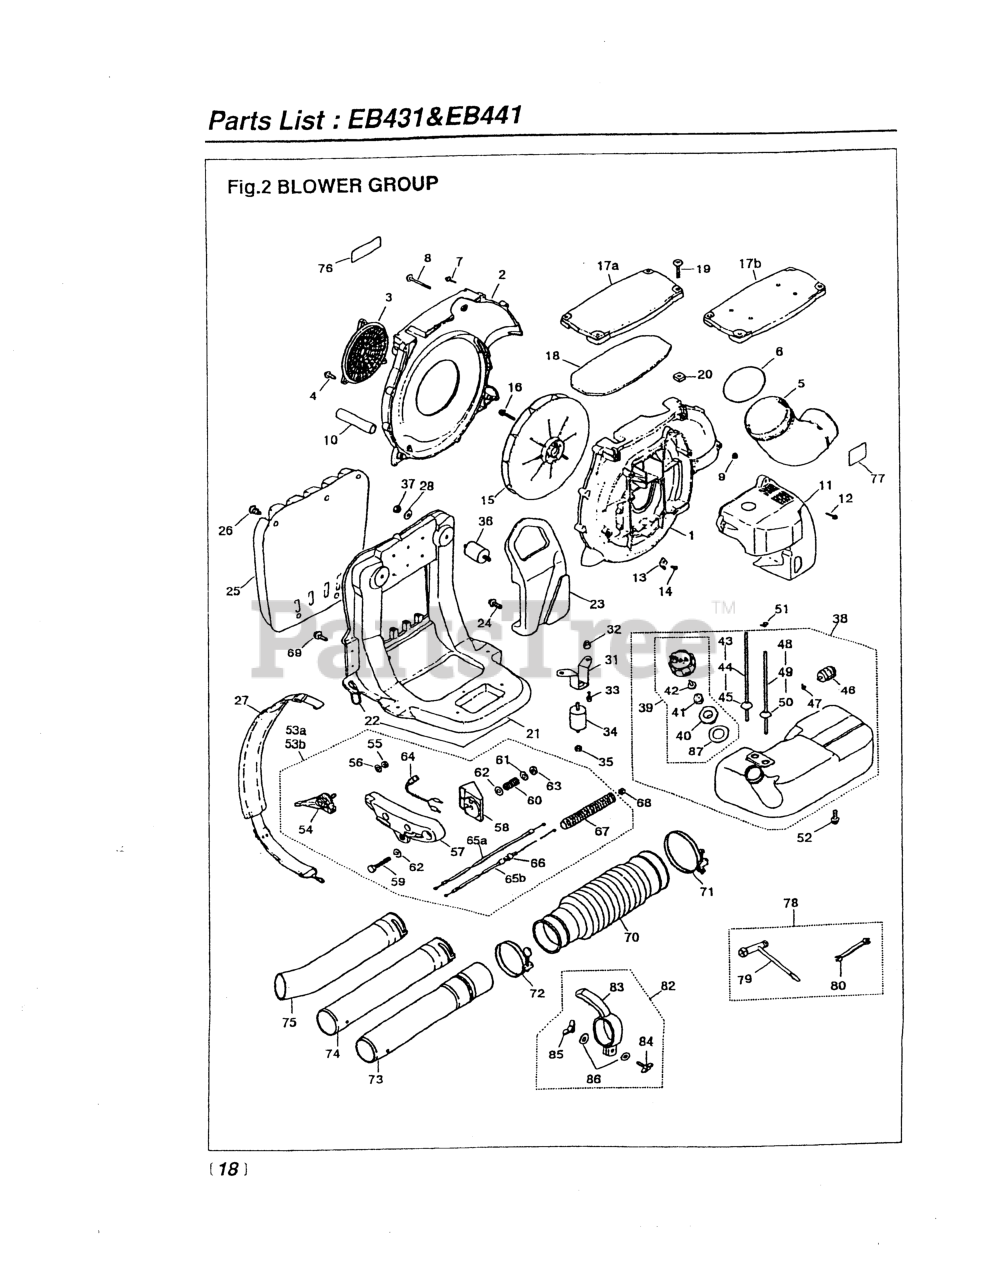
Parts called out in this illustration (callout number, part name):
1	CASE, VOLUTE
2	COVER, VOLUTE
3	NET, GUARD (RPLS-12222)
6	O-RING
7	SCREW
9	NUT (B)
11	COVER, ENGINE (RPLS-11210)
12	SCREW
15	FAN (REPLACES 3490-12110)
16	BOLT (RPLS 3405-12211)
17B	COVER (RPLS -13110)
18	COVER, PACKING
19	SCREW
20	NUT
22	RING (USE -21121)
23	HANGER (RPLS -21210)
25	PAD (RPLS -21310)
26	CLIP (RPLS 3490-21320)
28	WASHER, FLAT
31	BRACKET (RPLS -22510)
32	WASHER
33	SCREW, M5X20 (RPLS.1400-75510)
34	MOUNT (A) (RPLS 3490-22110)
35	NUT, M6 X 5
36	MOUNT (B) (RPLS 3405-22120)
37	NUT, M6 X 5
38	TANK ASSY (RPLS -23005)
39	CAP ASSY (RPLS -23202)
40	INNER CAP
43	PIPE (RPLS 3490-23410)
44	PIPE (USE 1696-85400)
45	GROMMET
46	FILTER ASSY
47	CLIP (REPLACES 2841-31280)
48	PIPE ASSEMBLY
49	PIPE (USE 1620-81710)
50	GROMMET
51	CLIP
52	SCREW, M5 x 12
53B	LEVER (EB441)
54	LEVER, THROTTLE
55	NUT (B)
56	WASHER, M5x.8(RPLS 01624-20508
58	BRACKET
59	BOLT
60	SPRING
61	WASHER
62	WASHER, FLAT
63	NUT, M6 X 5
64	SWITCH, STOP
65B	CABLE COMP,THROTTLE EB441
66	NUT, M6 X 5
67	TUBE (USE 5548-73310)
68	NUT, M6 X 5
69	BOLT
70	HOSE, FLEXIBLE
71	2756-51510 (RPLS. 07280-09832)
73	JOINT, SWIVEL
74	PIPE, EXTENSION
75	PIPE, BENT
78	TOOL SET
80	SPANNER, 8 X 10 (RPLS 2540- )
82	BLOWER ASSIST HANDLE
83	EBH100
84	BOLT, WING
85	NUT, WING
86	WASHER
87	PACKING (RPLS -85321)
